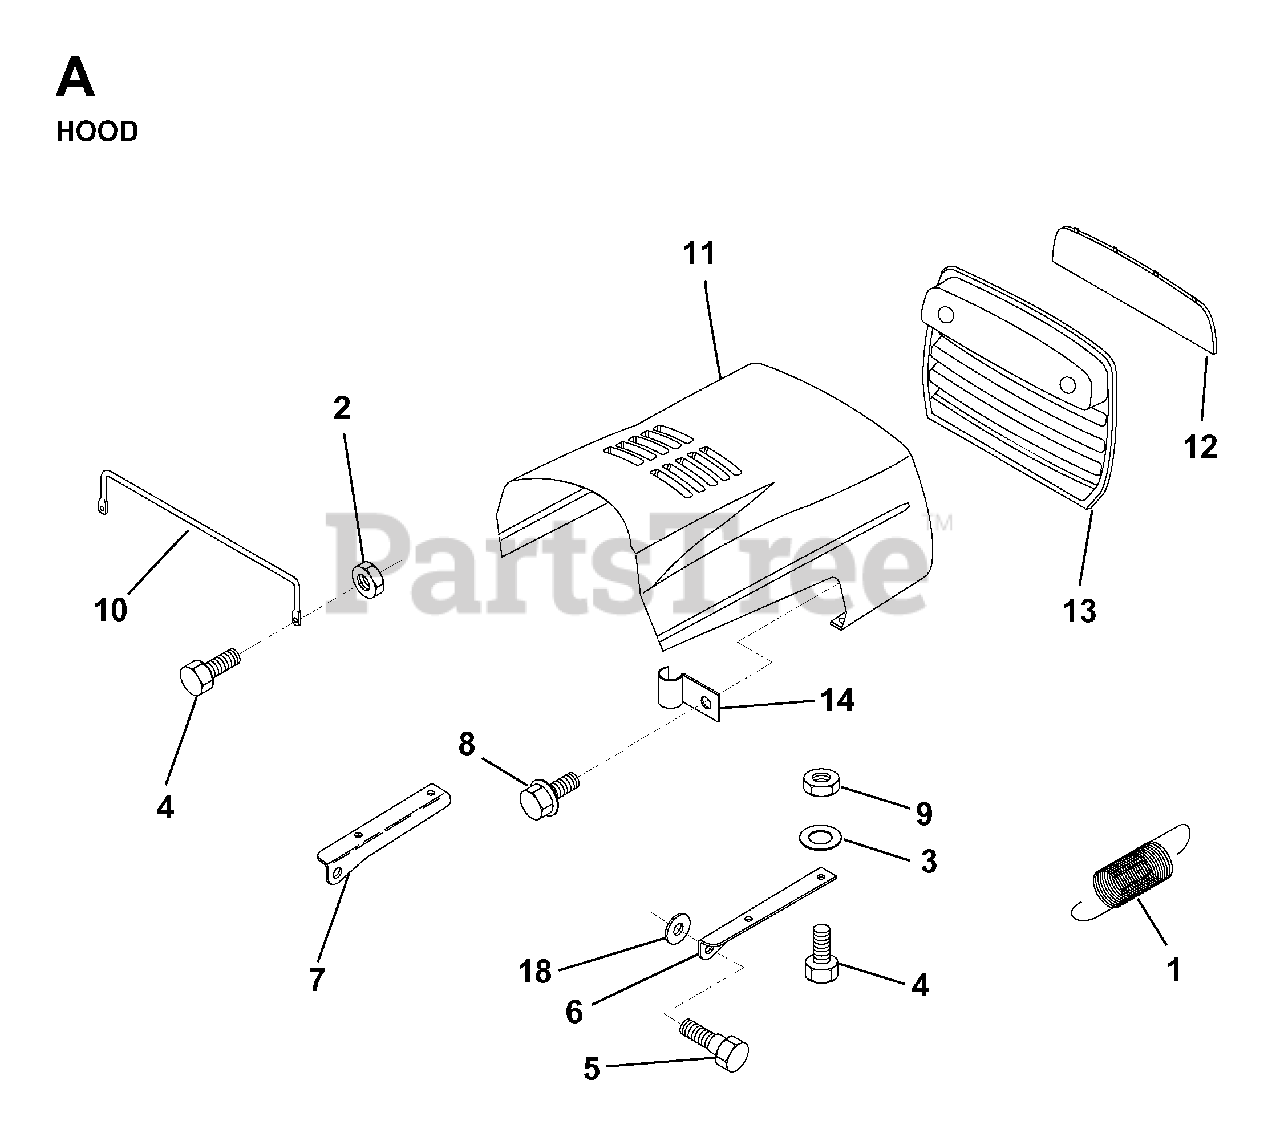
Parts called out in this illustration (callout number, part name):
1	EXT SPRING
2	NUT
4	BOLT
6	BRKT HOOD RH
7	BRKT HOOD LH
9	LOCKNUT
10	BRACE,HOOD
18	WASHER
